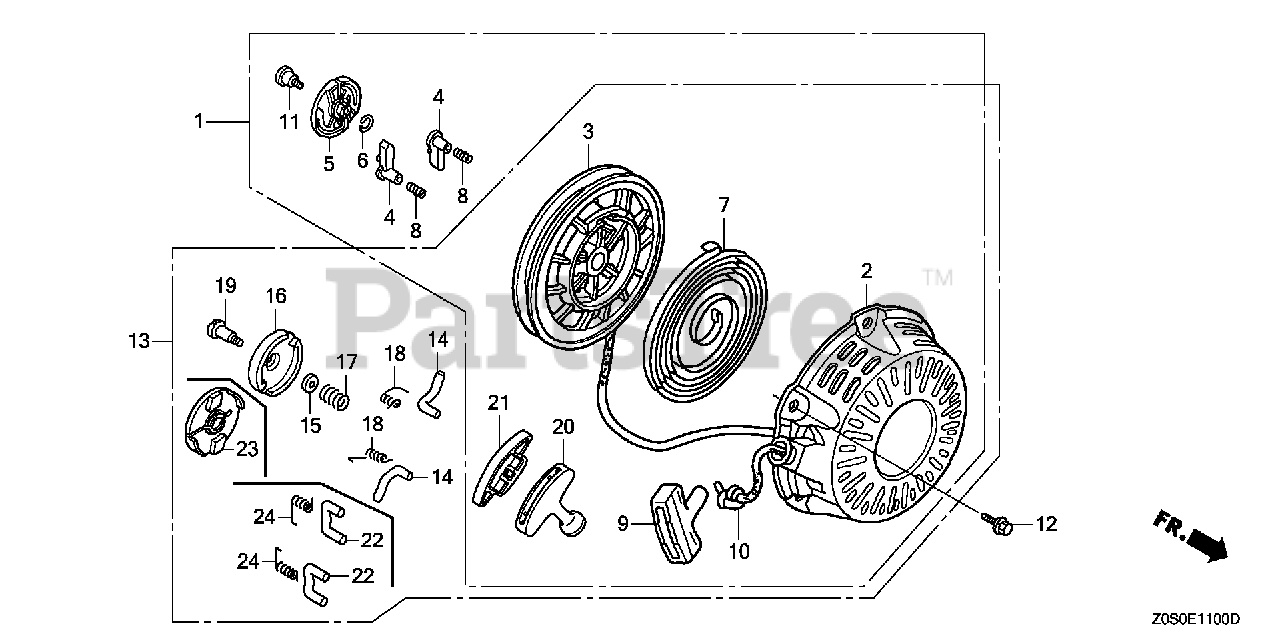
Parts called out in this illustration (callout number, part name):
2	CASE, RECOIL STARTER *R280* (POWER RED)
2	CASE, RECOIL STARTER *NH1* (BLACK)
3	REEL, RECOIL STARTER (BLACK)
7	SPRING, RECOIL STARTER
10	ROPE, RECOIL STARTER (#5X55")
12	BOLT, FLANGE (6X8)
13	STARTER ASSY., RECOIL *R280* (COO)(FOR U.S.A.) (POWER RED)
13	STARTER ASSY., RECOIL *NH1* (BLACK)
15	PLATE, FRICTION
17	SPRING, FRICTION
19	SCREW, SETTING
20	KNOB, RECOIL STARTER
21	KNOB, REINFORCEMENT
22	RATCHET, STARTER
23	GUIDE, RATCHET
24	SPRING, RETURN
